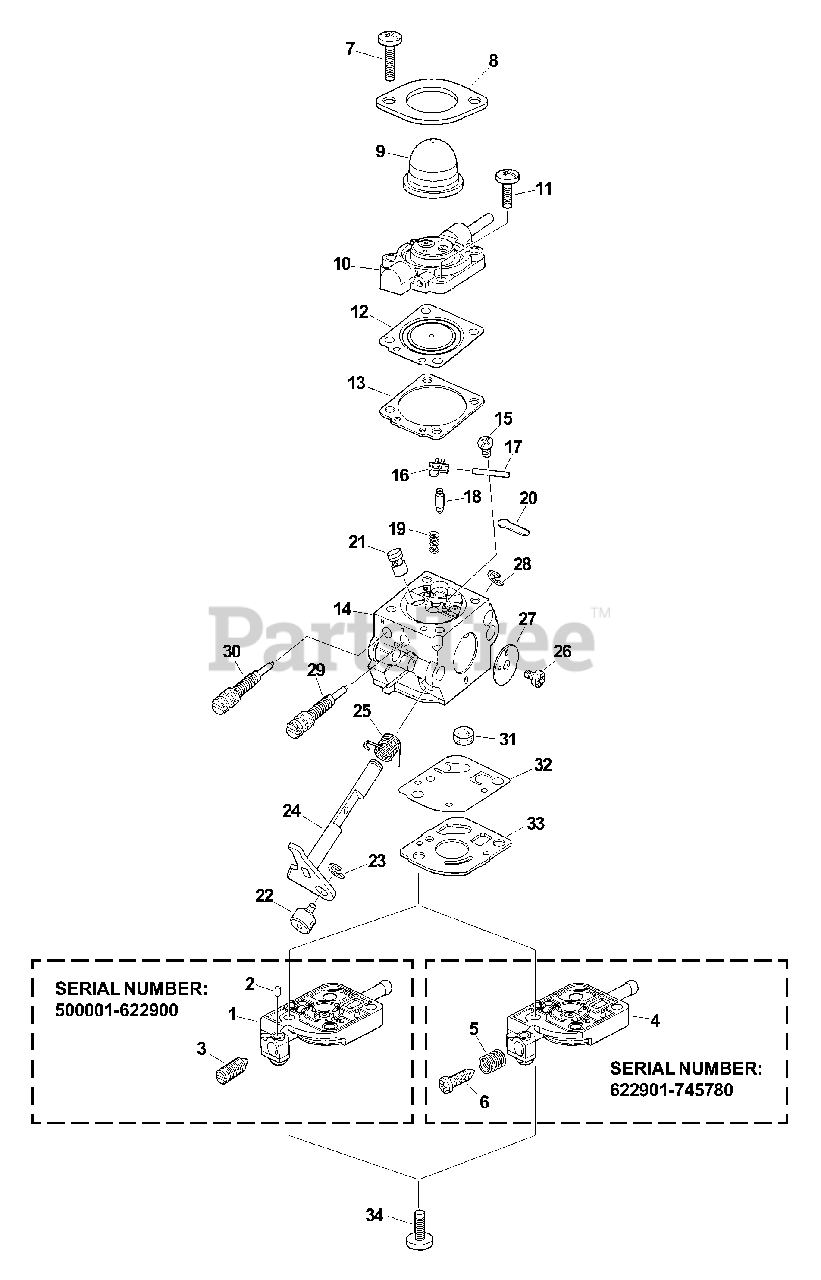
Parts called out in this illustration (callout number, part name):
1	COVER, PUMP
2	PIECE, FRICTION
3	SCREW, IDLE ADJUST
4	COVER, PUMP
5	SPRING
6	SCREW, IDLE ADJUST
7	SCREW
8	RETAINER, PURGE BULB
9	BULB, PURGE
10	BODY ASSY, PURGE
12	DIAPHRAGM, METERING
13	GASKET, METERING
14	BODY, CARBURETOR
16	LEVER, METERING
17	PIN, METERING LEVER
18	VALVE, INLET NEEDLE
19	SPRING, METERING LEVER
20	PLUG, WELCH
21	NOZZLE, CHECK VALVE
24	SHAFT, THROTTLE
25	SPRING, THROTTLE RETURN
27	VALVE, THROTTLE
29	NEEDLE, MIXTURE
30	NEEDLE, HIGH SPEED
31	STRAINER
